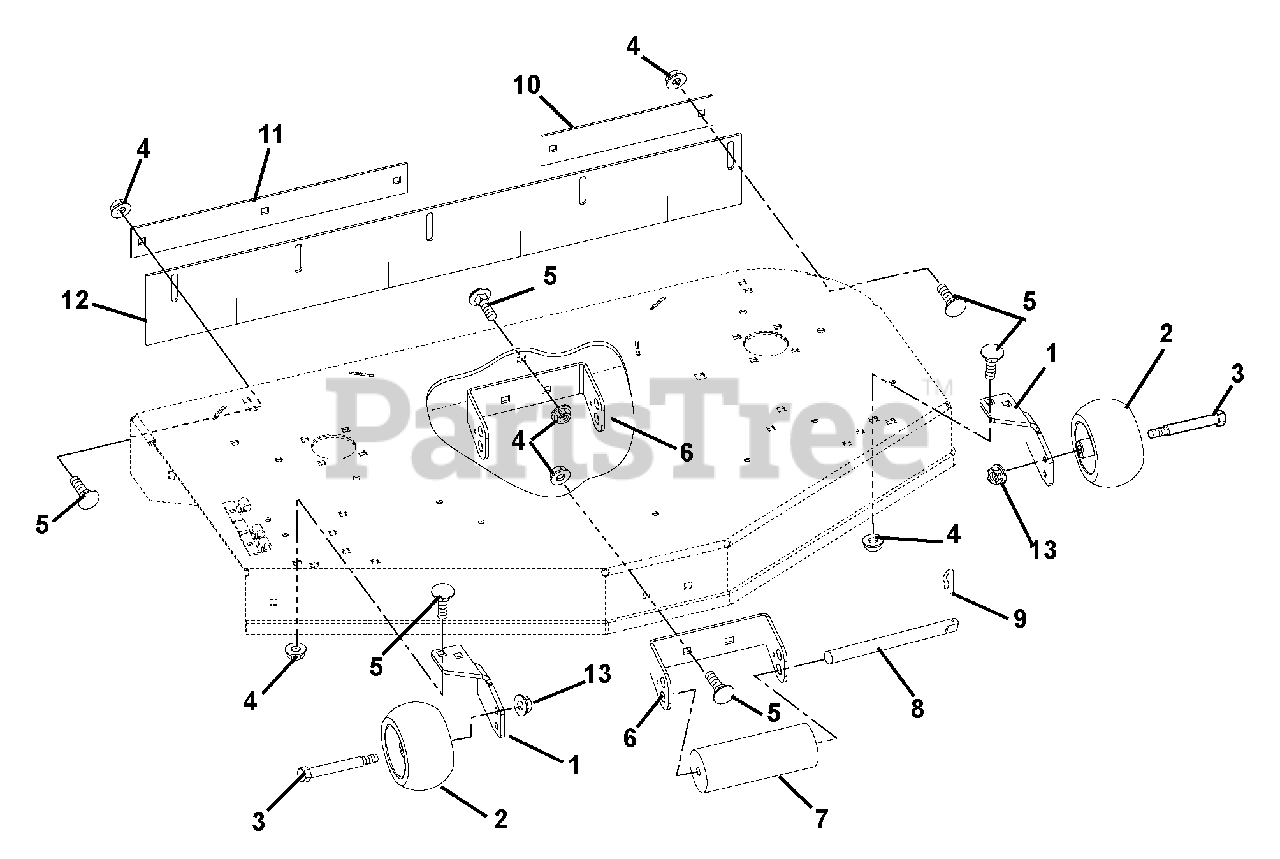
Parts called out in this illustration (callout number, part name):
1	Bracket, Anti-Scalp (044, 046, 048, 050)
2	Wheel 5 x 3 (044, 046, 048, 050)
3	Bolt, Shoulder .38-16 x 2.50 Hex Washer Head Grade 5 (044, 046, 048, 050)
4	Nut .38-16 Flange Nyloc (044, 046, 048, 050)
4	Nut .38-16 Flange Nyloc (042)
5	Bolt-Round Head Square Neck .38-16 x 1.00 Grade 5 (044, 046, 048, 050)
5	Bolt- Round Head Square Neck .38-16 x 1.00 Grade 5 (042)
6	Bracket, Roller Mount (044, 046, 048, 050)
6	Bracket, Roller Mount (042)
7	Roller (044, 046, 048, 050)
7	Roller (042)
8	Pin, Roller (044, 046, 048, 050)
8	Pin, Roller (042)
9	Pin, Spring Clip (044, 046, 048, 050)
9	Pin, Spring Clip (042)
10	Bar, Left Hand Retainer Striper (044, 046, 048, 050)
11	Bar, Retaining Striper (046)
11	Bar, Retaining Striper (048, 050)
11	Bar, Retaining Striper (044)
12	Striper, Rubber-44" (046)
12	Striper, Rubber-48" (048)
12	Striper, Rubber-52" (050)
12	Striper, Rubber-40" (044)
13	Nut-Locking-Top-Flange .38-16 (044, 046, 048, 050)
